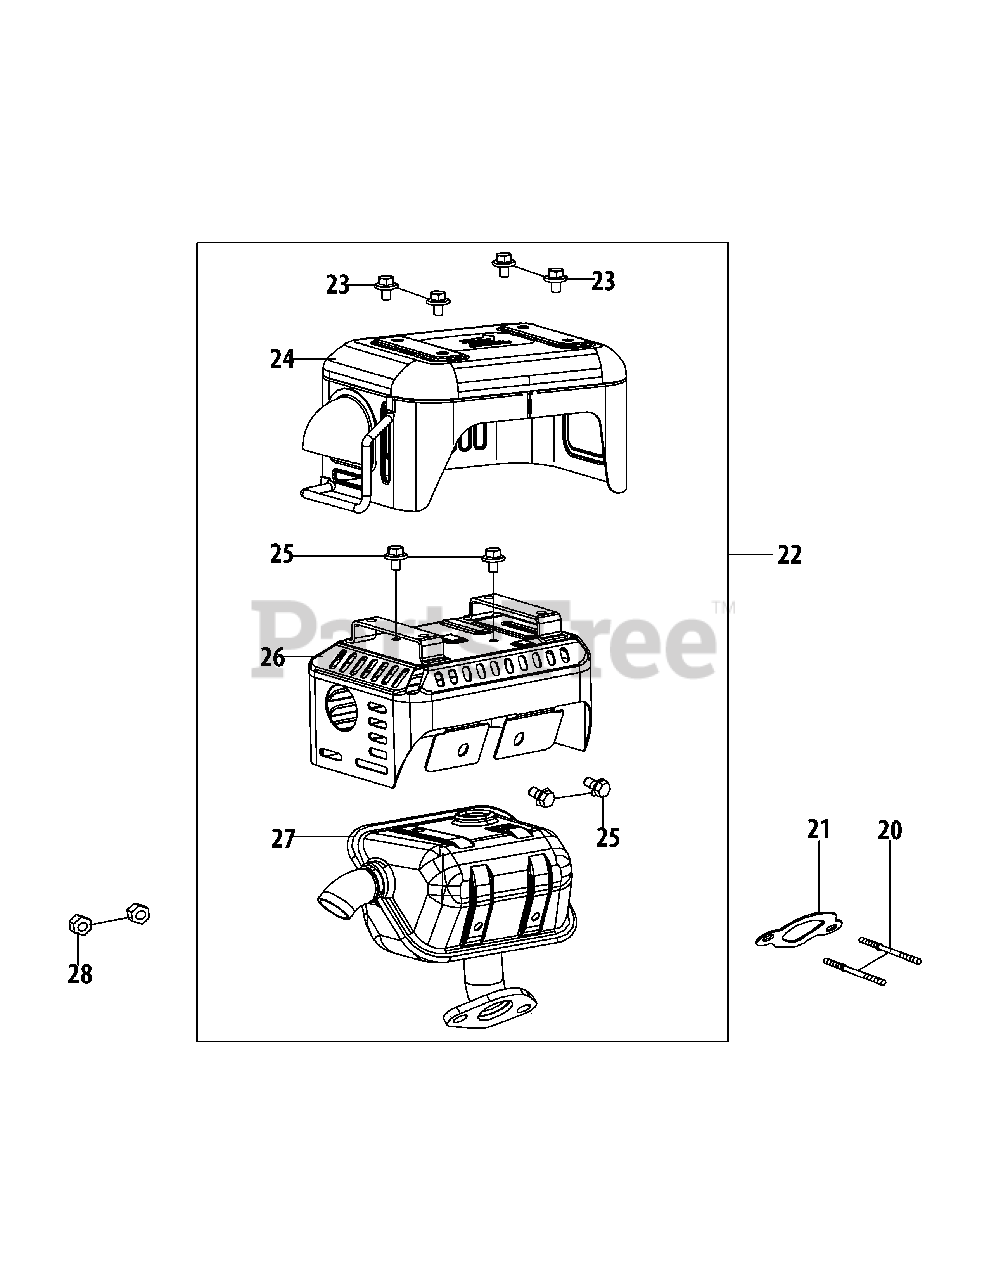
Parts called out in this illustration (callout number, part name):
20	Stud M8×34
21	Muffler Gasket
22	Muffler
23	Bolt M5×8
24	Muffler Guard
25	Bolt M5×12
26	Muffler Shield
27	Muffler Body
